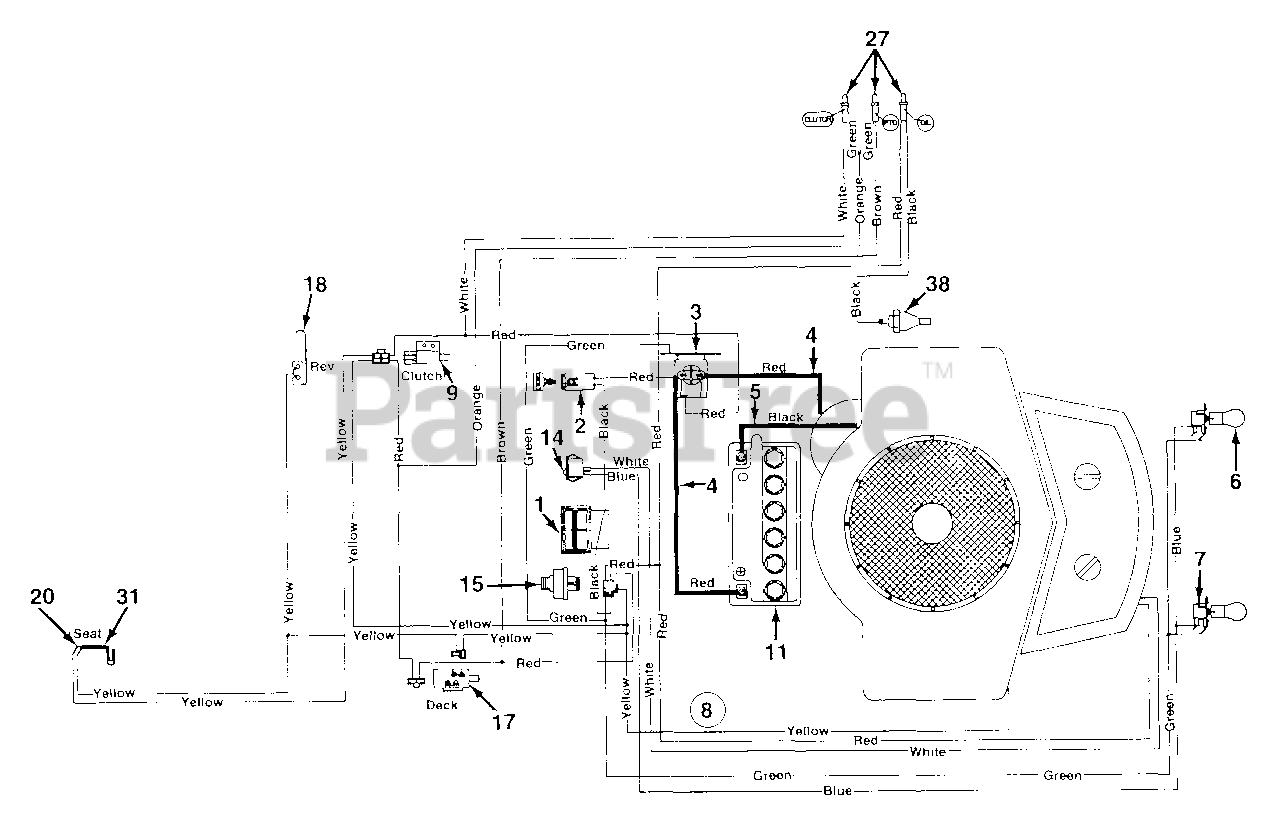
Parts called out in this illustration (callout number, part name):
1	Ammeter
2	Fuse 7.5 Amp
2	Fuse 20 Amp
3	Solenoid
4	Wire
5	6 Ga. Black Wire 7.5" Lg.
6	Bulb
7	Socket
8	Wire Harness
9	Safety Switch (Clutch)
11	Battery (275 Cold Crank Amps)
14	Light Switch
15	Ignition Switch
17	Safety Switch (Deck)
18	Spring Lever
20	Safety Switch (Seat)
27	Bulb
31	Safety Switch (Seat)
38	Oil Pressure Switch
